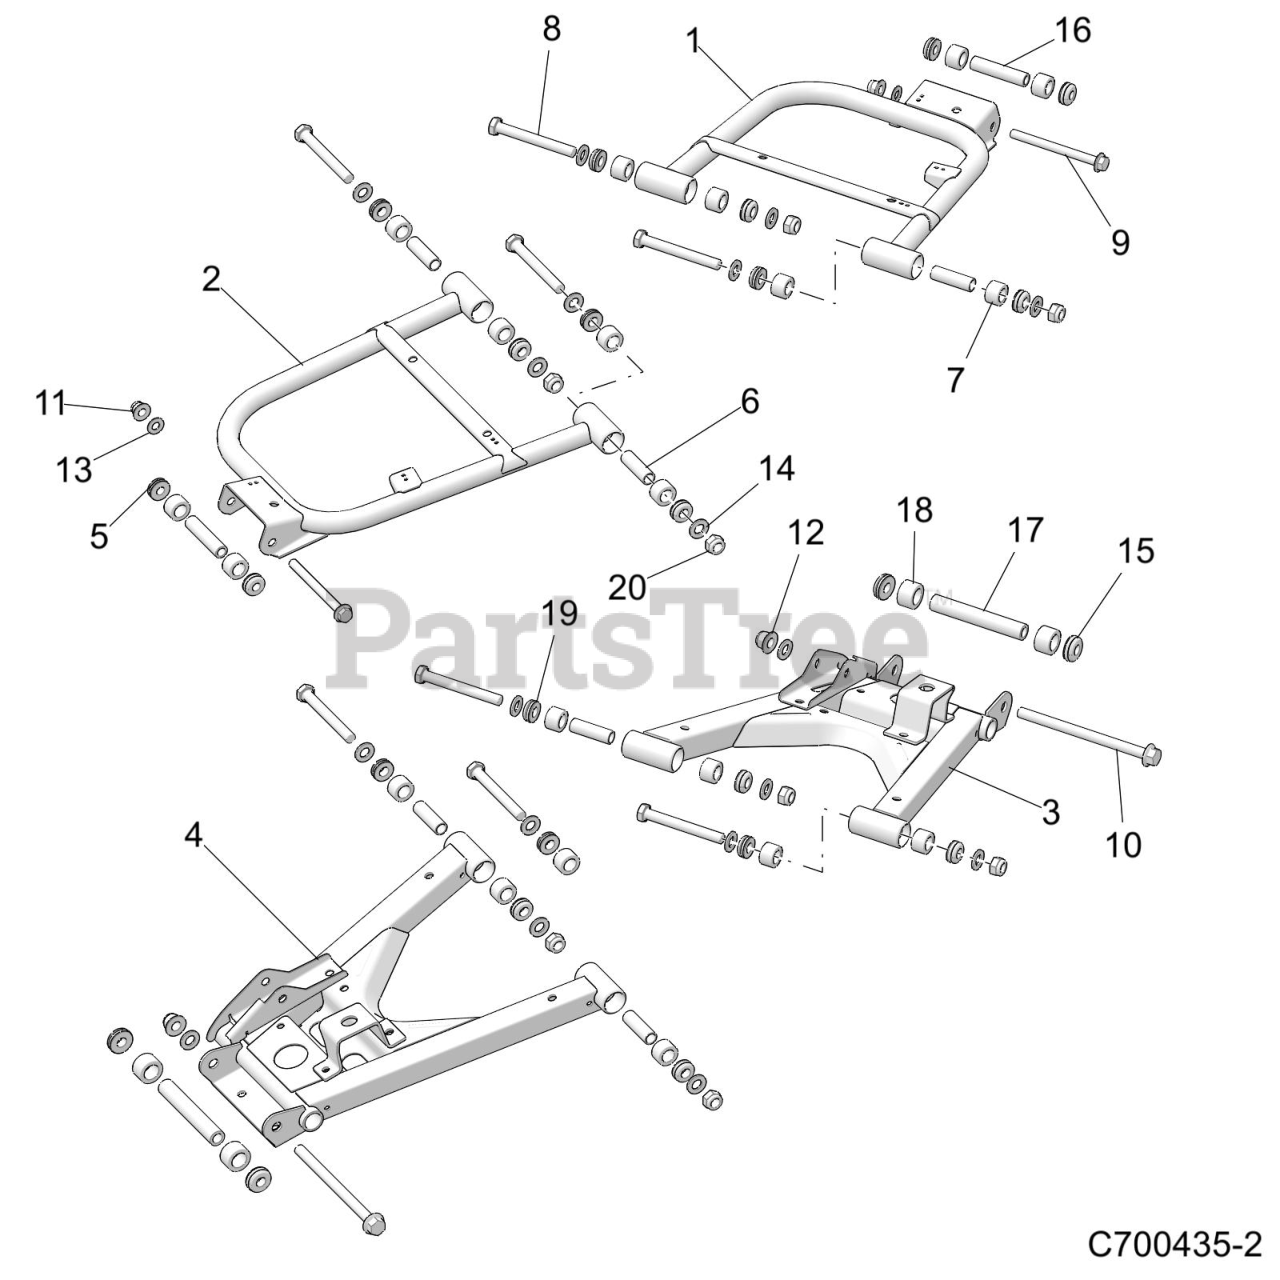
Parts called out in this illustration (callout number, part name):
1	WELD-CONTROL ARM,RR,UPR,LH,BLK
2	WELD-CONTROL ARM,RR,UPR,RH,BLK
3	WELD-CONTROL ARM,RR,LWR,LH,BLK
4	WELD-CONTROL ARM,RR,LWR,RH,BLK
5	ASM-PIVOT CAP,SEALED,M10
6	SHAFT-PIVOT,SHORT,M12
7	BUSHING-STANDARD,SUSP,M10
8	SCR-HH-M12X1.75X100 10.9 ZPC
9	SCR-HXFL-M10X1.25X115 10.9 ZOD
10	SCR-HXFL-M12X1.5X170 10.9 ZOD
11	NUT-M10X1.25,FLG,NYLOC-OLIVE D
12	NUT-M12X1.5,FLG,NYLOC-OLIVE D
13	WASHER,3/8 FW
14	WSHR-13.0X24.0X2.5 ZPC
15	ASM-PIVOT CAP,SEALED,M12
16	SHAFT-PIVOT,SHORT,M10
17	SHAFT-PIVOT,LONG,M12
18	BUSHING-STANDARD,SUSP,M12
19	ASM-PIVOT CAP,SEALED,M12
20	NUT-NYLOK,M12X1.5,0600110
